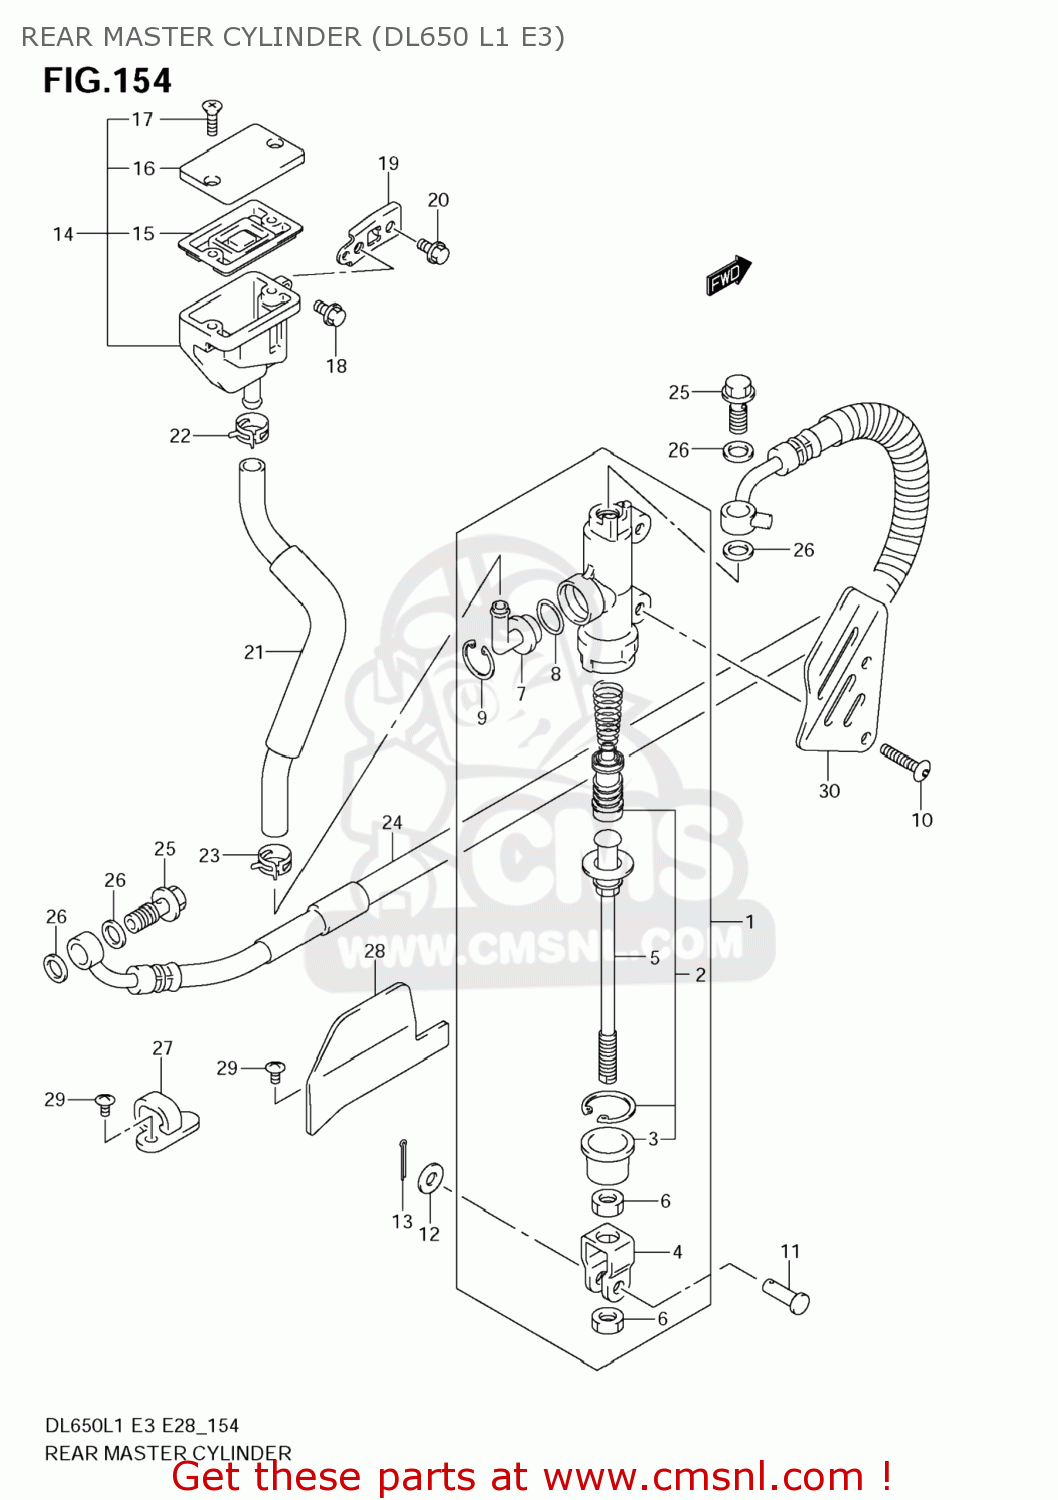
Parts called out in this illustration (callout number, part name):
1	CYLINDER ASSY,RR MASTER
2	PISTON/CUP SET
3	BOOT
4	YOKE
5	ROD,PUSH
6	NUT
7	CONNECTOR
8	O RING
9	CIRCLIP
10	SCREW(6X25)
11	PIN(6X18.2)
12	WASHER
13	PIN
14	TANK ASSY,RR RESERVOIR
15	DIAPHRAGM
16	CAP
17	SCREW
18	BOLT
19	BRACKET,RR RES
20	BOLT
21	HOSE,RR RESERVOIR TANK
22	CLIP
23	CLIP
24	HOSE,RR BRAKE
25	BOLT UNION
26	WASHER(10X15X1.5)
27	GUIDE,REAR BRA
28	GUIDE,RR BRAKE HOSE FR
29	SCREW
30	COVER,RR MASTER CYLINDER
